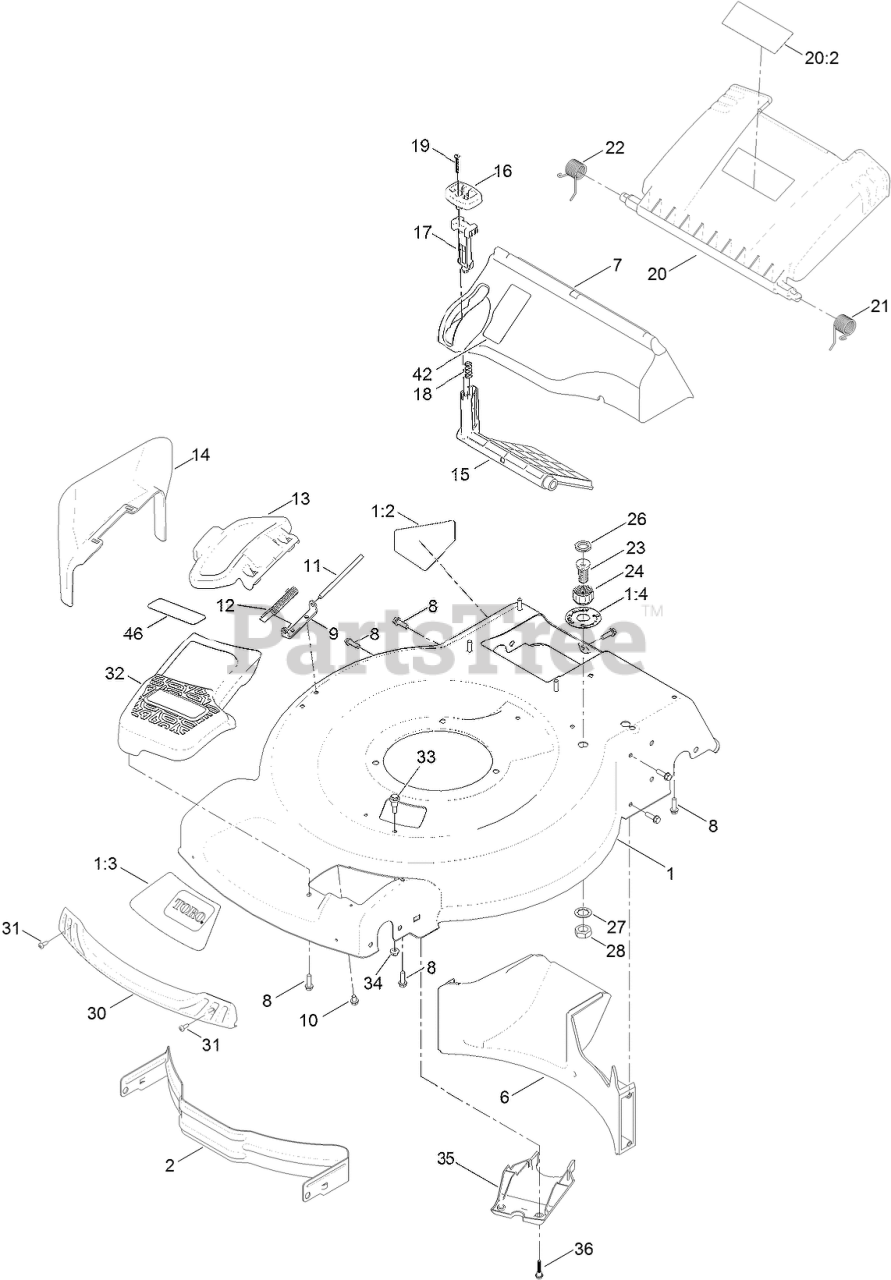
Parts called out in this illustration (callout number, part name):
1	HOUSING ASM
1:2	DECAL-DANGER
1:3	DECAL-DECK
1:4	DECAL-PORT, WASHOUT
2	BAFFLE-FRONT
6	BAFFLE-REAR
7	CHUTE-RECYCLE
8	SCREW-HWH
9	BRACKET-COVER
10	SCREW-HWH
11	ROD-COVER
12	SPRING-TORSION
13	DEFLECTOR-SIDE
14	CHUTE-DISCHARGE, SIDE
15	DEFLECTOR-RECYCLE
16	KNOB-RECYCLE
17	LATCH-RECYCLE
18	SPRING-COMPRESSION
19	SCREW-PPH
20	REAR DOOR ASM
20:2	DECAL-WARNING
21	SPRING-TORSION
22	SPRING-TORSION
23	PORT-WASHOUT
24	COUPLING-HOSE, WASHOUT PORT
26	WASHER-SEAL, WASHOUT PORT
27	WASHER-TOOTH, INTERNAL
28	NUT-JAM
30	BUMPER
31	SCREW-FORMING, THREAD
32	COVER-BELT, FRONT
33	BOLT-SHOULDER
34	NUT-LOCK, NI
35	COVER-BELT, FRONT
36	SCREW-SHOULDER, HHF
46	DECAL-COVER
